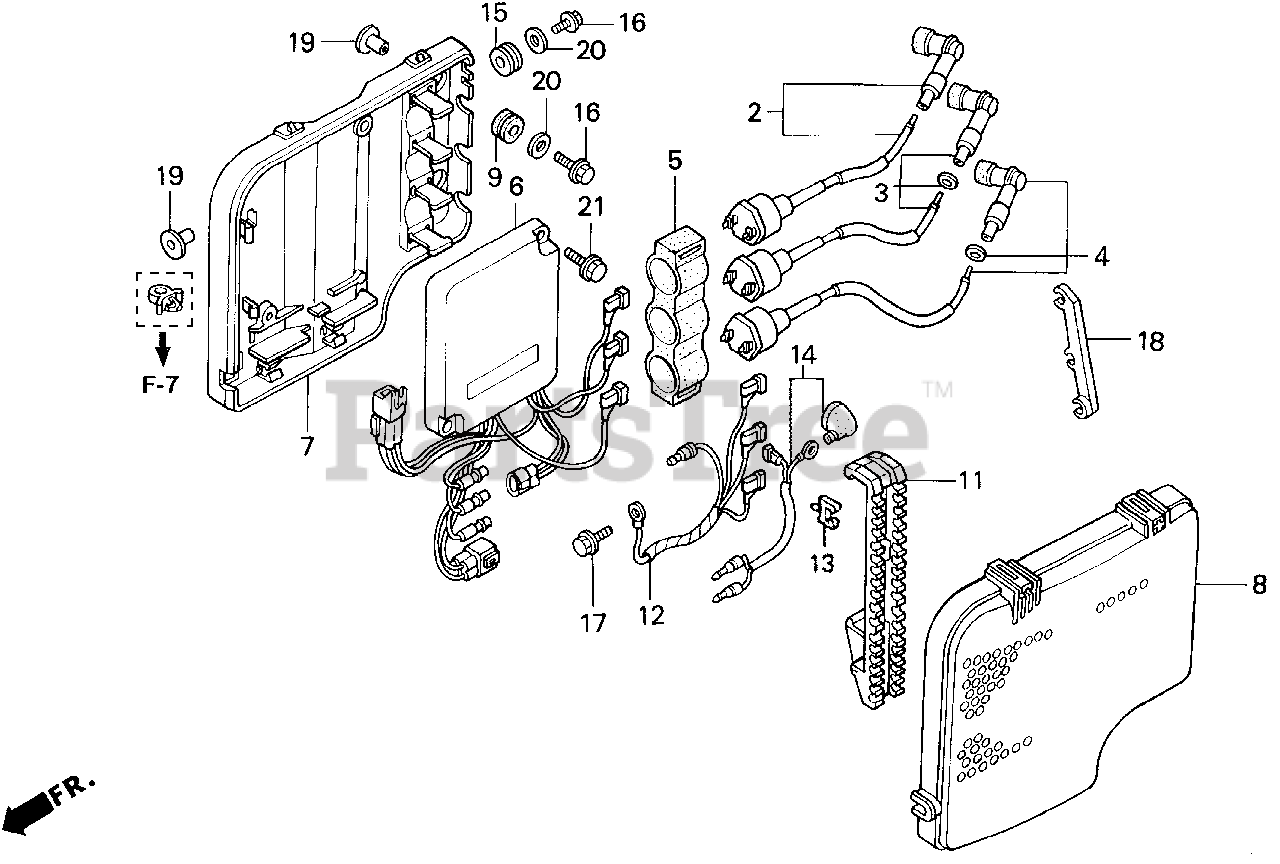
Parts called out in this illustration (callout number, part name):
2	COIL, IGNITION (1)
3	COIL, IGNITION (2)
4	COIL, IGNITION (3)
5	SUSPENSION, IGNITION COIL
6	MODULE, IGNITION CONTROL (CDI)
7	CASE, IGNITION CONTROL MODULE
8	COVER, IGNITION CONTROL MODULE
8	COVER, IGNITION CONTROL MODULE (CDI)
9	GROMMET, IGNITION CONTROL MODULE CASE (B)
11	BRACKET, CONNECTOR (A)
12	WIRE ASSY., GROUND
13	CLIP, TURN SIGNAL WIRE
14	WIRE, SWITCH
15	GROMMET, CASE (LOWER)
16	BOLT, FLANGE (6X25)
17	BOLT, FLANGE (6X12)
18	CLIP, IGNITION WIRE
19	COLLAR, IGNITION CONTROL MODULE CASE
19	COLLAR, MODULE IGNITION CONTROL CASE (CDI)
20	WASHER, PLAIN (6MM)
21	BOLT, FLANGE (6X20)
